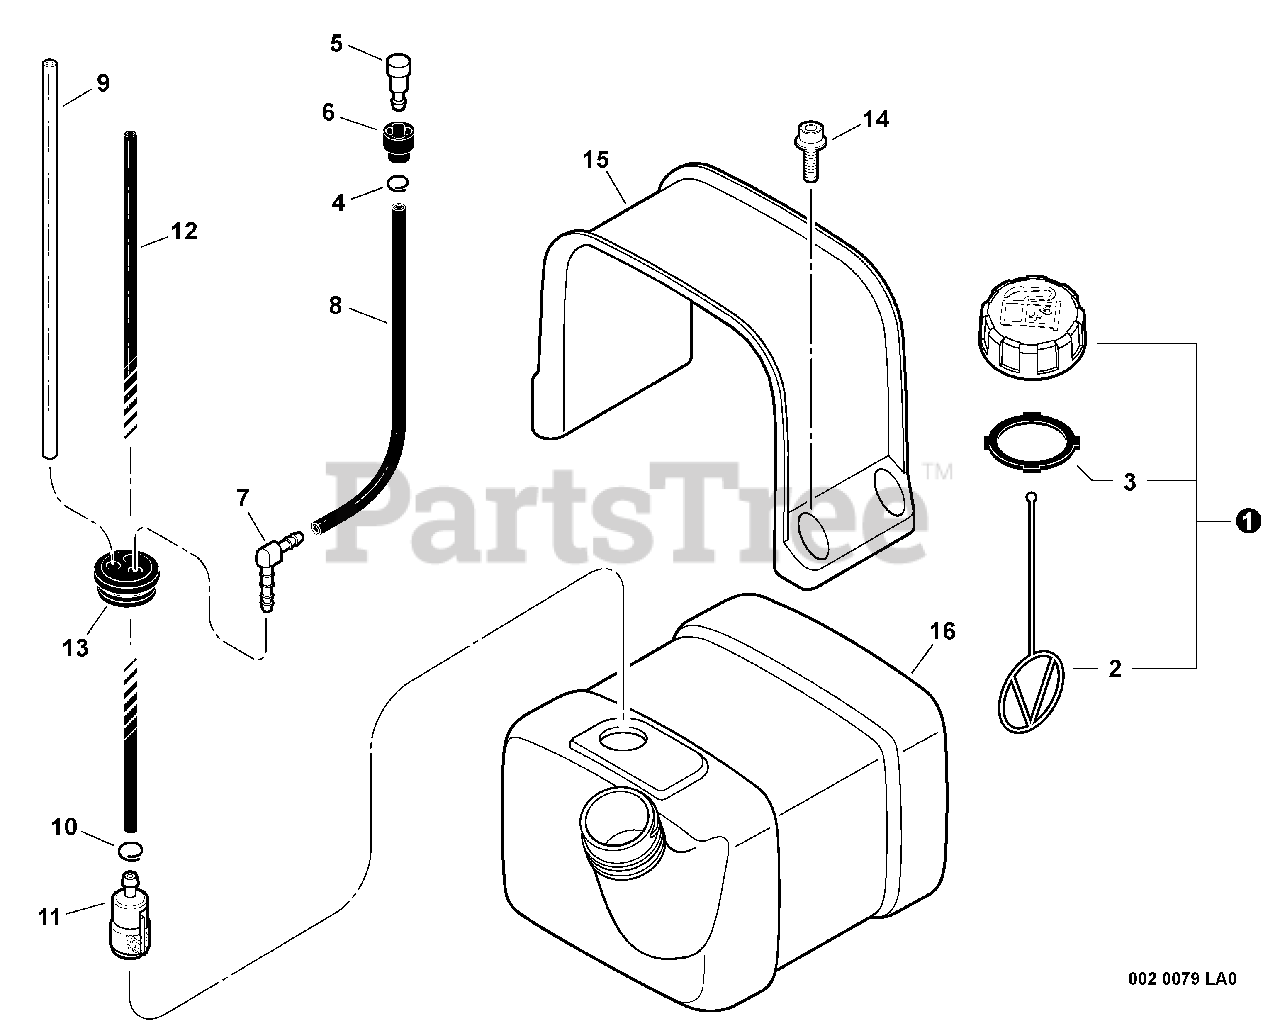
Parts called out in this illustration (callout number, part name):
1	CAP ASSY, FUEL
2	CONNECTOR, CAP L= 100 MM
3	GASKET, FUEL CAP
4	CLIP Ø6.5 MM
5	VENT ASSY
6	HOLDER, VENT
7	CONNECTOR, PIPE Ø5.4
8	PIPE, VENT 3×6×145 MM
9	PIPE, FUEL RETURN 3×6×145
10	CLIP Ø6.5 MM
11	FILTER, FUEL
12	PIPE, FUEL 3×6×230
13	GROMMET, FUEL
14	BOLT 5×16
15	BRACKET, FUEL TANK
16	TANK, FUEL
